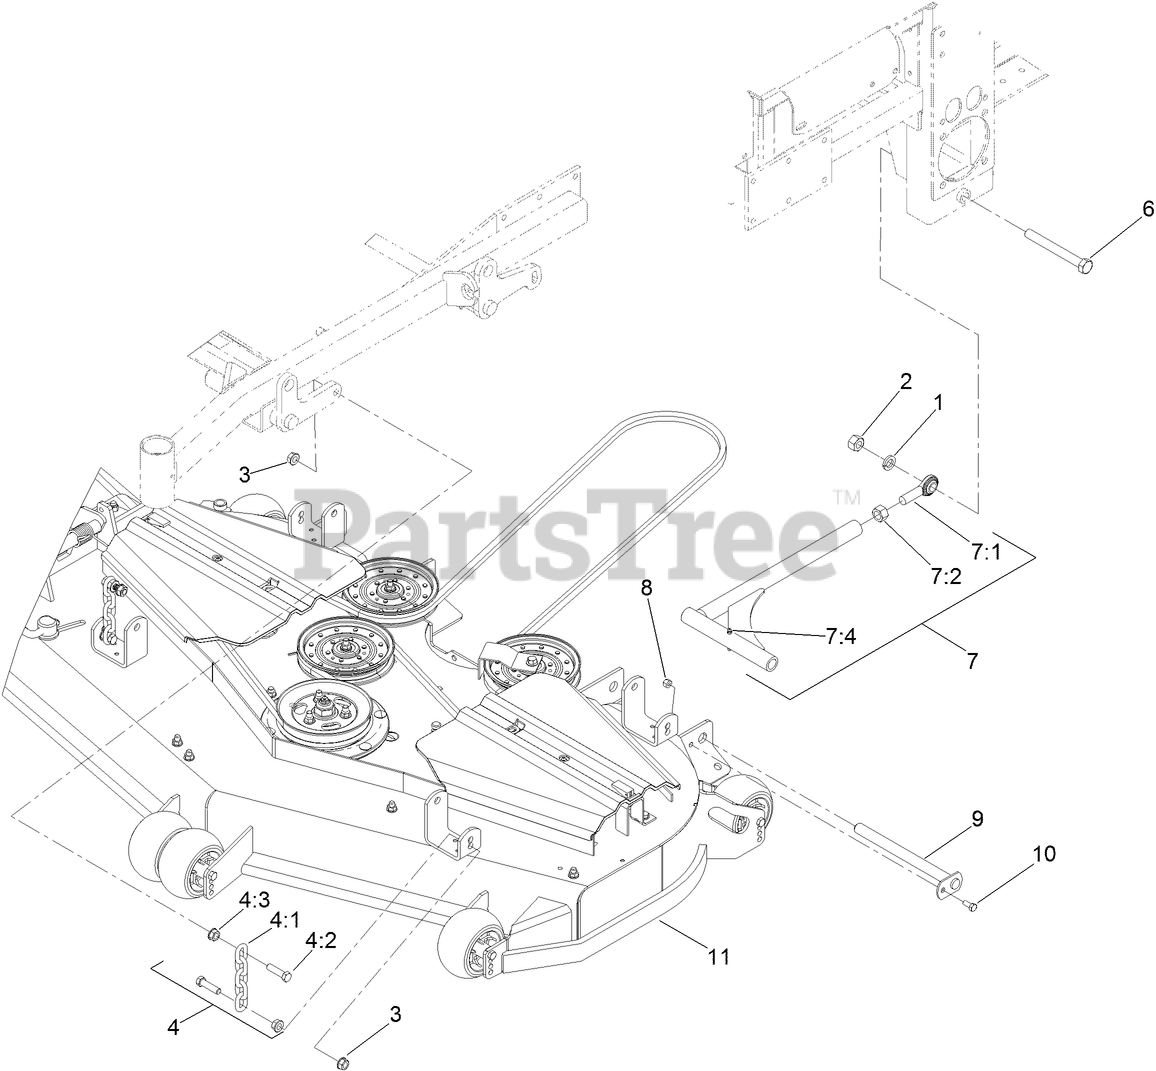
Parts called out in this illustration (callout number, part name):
1	WASHER-LOCK
2	NUT-HEX
3	NUT-HF
4	DECK CHAIN ASM
4:1	CHAIN-LIFT, DECK
4:2	SCREW-HH
4:3	NUT-HF
6	SCREW-HH
7	STRUT ASM
7:1	BALLJOINT-SPHERICAL
7:2	NUT-HEX
8	NUT-LOCK, NI
9	PIN-STRUT
10	SCREW-HH
11	DECK ASM
